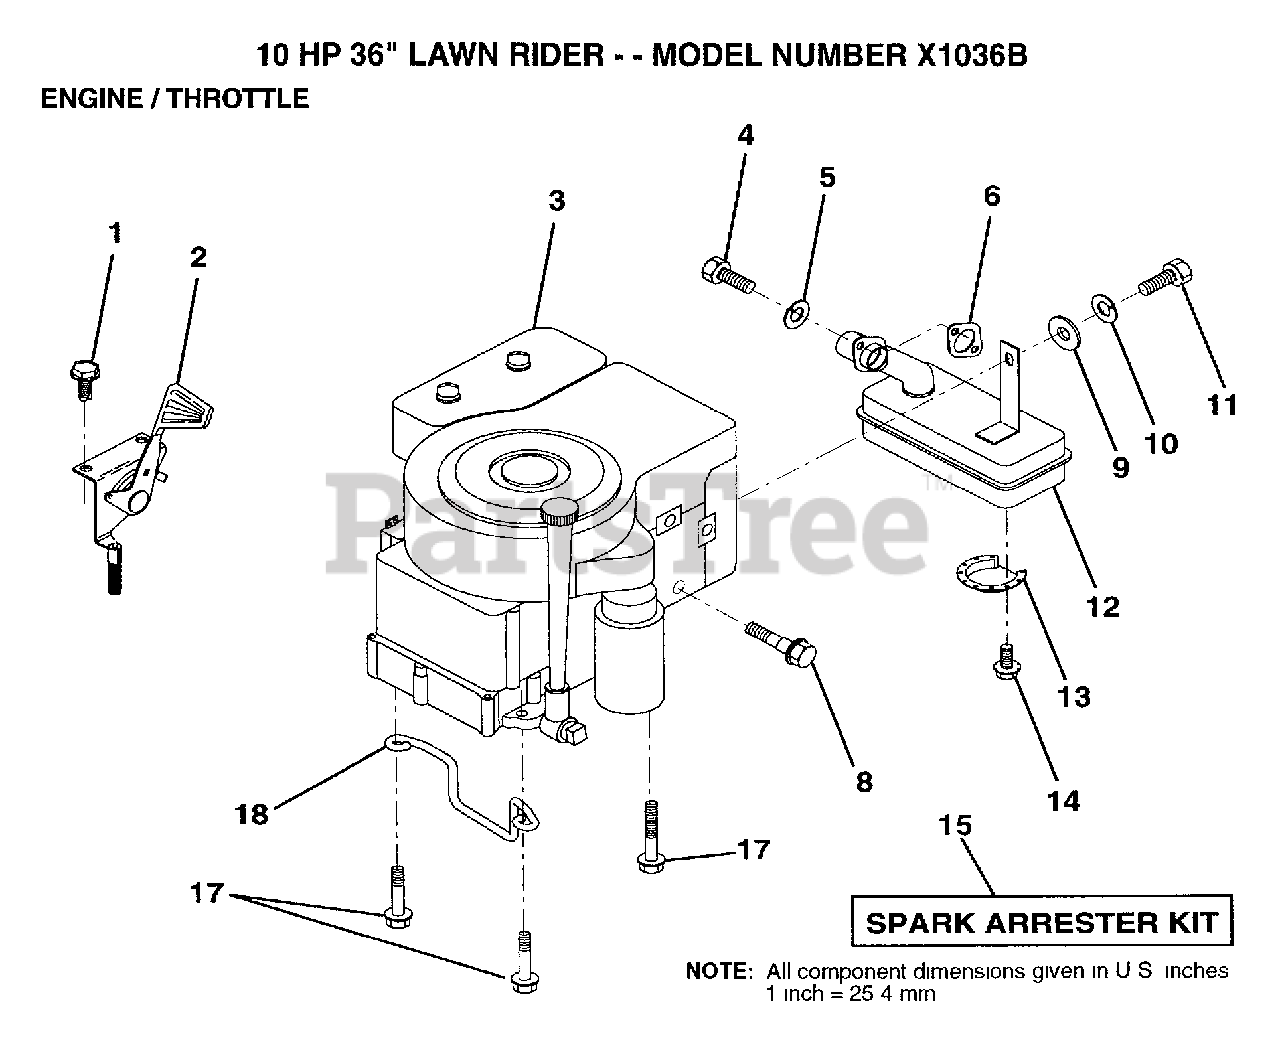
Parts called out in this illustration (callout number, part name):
2	THROTTLE CONTROL
3	ENGINE, B&S 10 HP
4	SCREW
5	LOCKWASHER
8	BOLT T
10	LOCKWASHER
12	MUFFLER
13	DEFLECTOR.222573
17	SCREW LT
18	"KEEPER,DR BELT GR"
